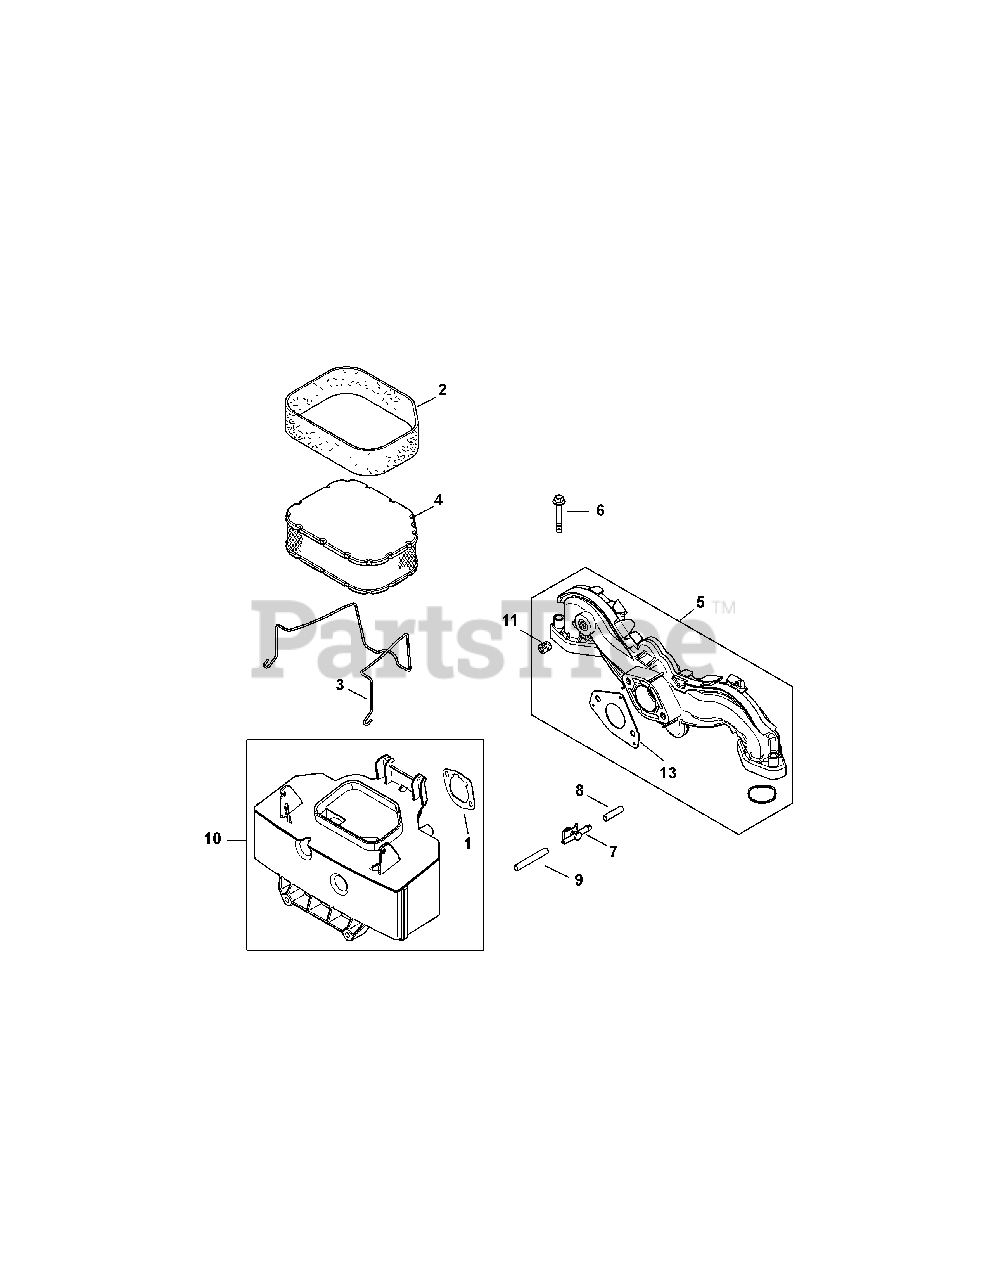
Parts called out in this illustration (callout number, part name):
1	Air Cleaner Base Gasket
2	Pre-Cleaner Element
3	Air Cleaner Element Latch
4	Air Filter Element
5	Intake Manifold Kit
6	Flange Screw, M6 x 1.0 x 40
7	Evaporative Connector
8	Evaporative Mask
9	Evaporative Hose, 20"
10	Air Cleaner Base
11	Pipe Plug, 1/8
12	Carburetor Gasket
13	Intake Port O-Ring
